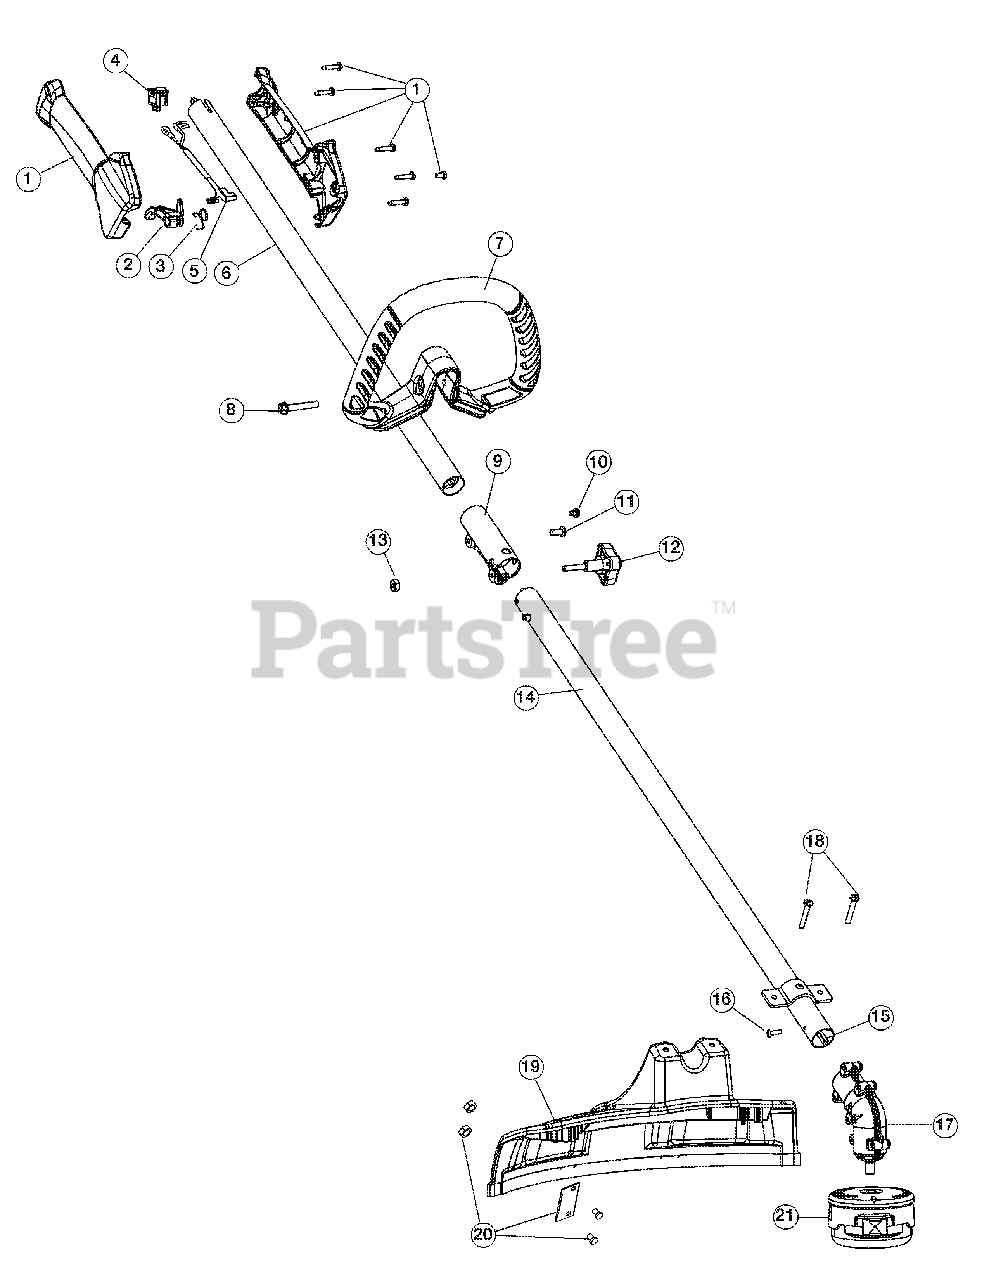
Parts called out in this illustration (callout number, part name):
1	Throttle Housing Assembly (Incl. Ref No. 2-4)
2	Throttle Trigger
3	Throttle Trigger Spring
5	Throttle Cable Assembly
6	Upper Drive Shaft Housing Assembly
7	Deluxe D-Handle Assembly (Incl. Ref No. 8)
9	Split Boom Coupler (Incl. Ref No. 10-13)
12	Adjustment Knob (Incl. Ref No. 13)
13	Knob Retaining Nut
14	Lower Drive Shaft Housing Assembly
15	Lower Flexible Drive Shaft
16	Anti-Rotation Screw
17	Gear Box Assembly (Incl. Ref No. 16)
18	Shield Mounting Screws
19	Shield Assembly (Incl. Ref No. 20)
20	Blade Assembly
21	Cutting Head Assembly
